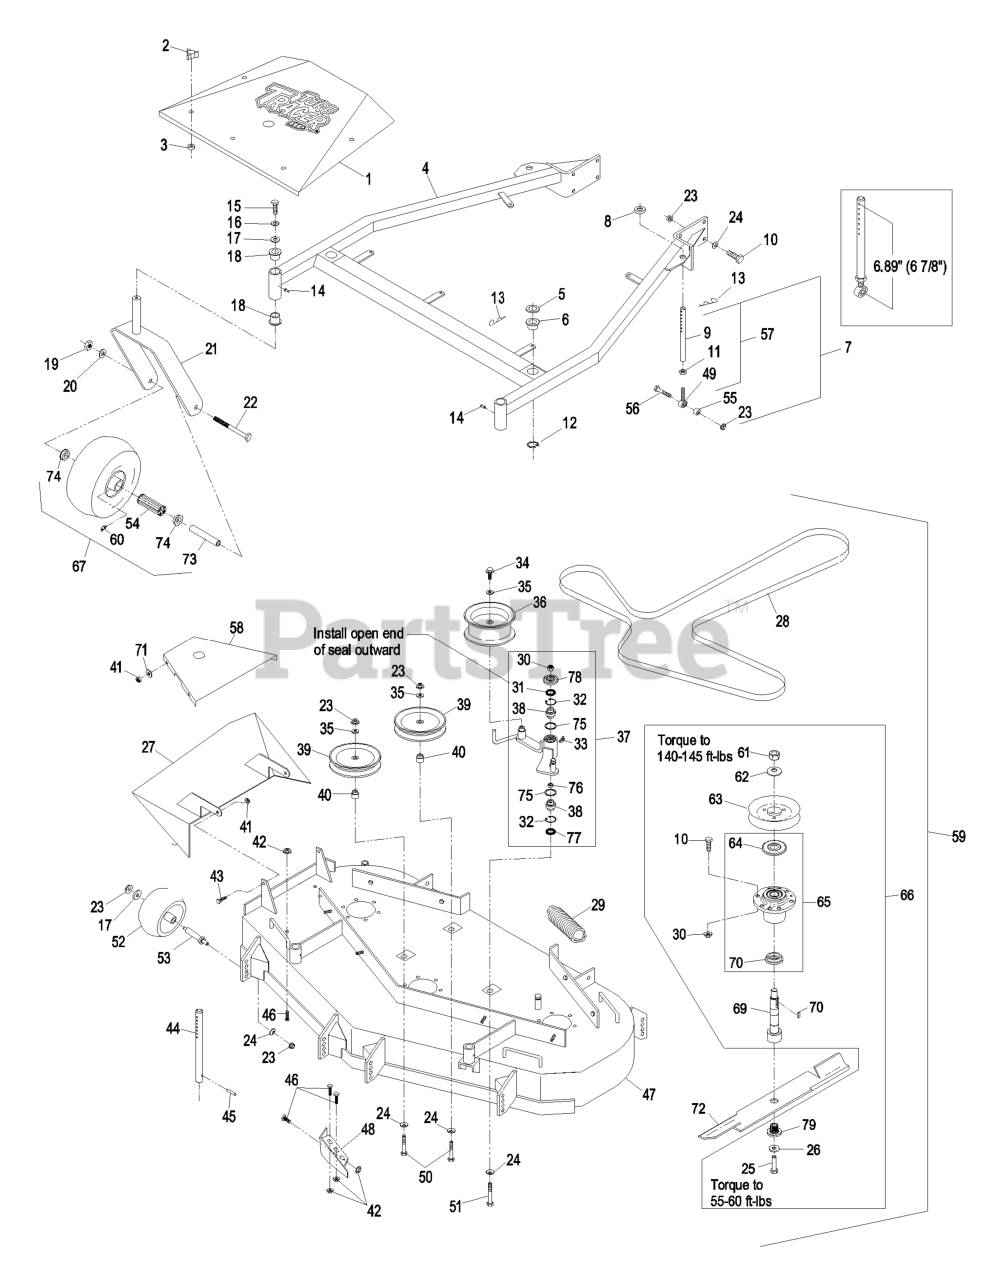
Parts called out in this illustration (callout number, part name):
2	KNOB-3 PRONG
4	SUPPORT,DECK W/BUSHINGS
5	SPACER-DECK SUPPORT
6	BUSHING-DECK
9	LINK,SUPPORT
10	SCREW-HH
11	NUT-HEX
12	RING-RETAINING
13	PIN,HAIR COTTER
14	FITTING-GREASE
15	SCREW-HH
16	WASHER-LOCK
18	BEARING-FLANGED
19	NUT-HH
20	WASHER-LOCK
22	SCREW-HH
23	NUT-HHF, WHIZ
24	WASHER-BELLEVILLE
25	SCREW-HH
26	WASHER-SPRING
27	WLD,CHUTE DISCHARGE
28	BELT,DECK DRIVE
30	NUT-LOCK, NI
31	SEAL-LIP, SINGLE
32	RING-SNAP
33	FITTING-GREASE, 90 DEG
34	SCREW-HHF
35	WASHER-FLAT
37	KIT, DECK IDLER TTHP48&52
38	BEARING-SPHERICAL
39	PULLEY-IDLER
40	BUSHING-IDLER
41	NUT-LOCK, NI
43	SCREW-HH
44	ROD,DECK SUPPORT
46	SCREW-HH
47	ASM,DECK W/DECALS TTHP52
48	WLD,BAFFLE DISCHARGE
49	BALLJOINT
50	SCREW-HH
51	SCREW-HH
52	ROLLER-SCALP, ANTI
54	BEARING
56	SCREW-HH
58	SHIELD,SIDE BELT 52
59	Asm, Deck Complete
60	FITTING-GREASE
61	NUT-HH
63	SHEAVE,W/HUB 5.72
64	GUARD-BEARING, TOP
65	KIT, CUTTER HOUSING
66	ASM, CUTTER HSG
67	KIT, SP CASTER WHEEL REPL
68	SPACER-GUARD, BOTTOM
69	KIT, SPLINED SPINDLE 103-
70	KEY-RECTANGLE
71	WASHER-FLAT
74	BUSHING
77	SEAL-LIP, DOUBLE
78	GUARD-TOP
79	BUSHING,SPLINED
